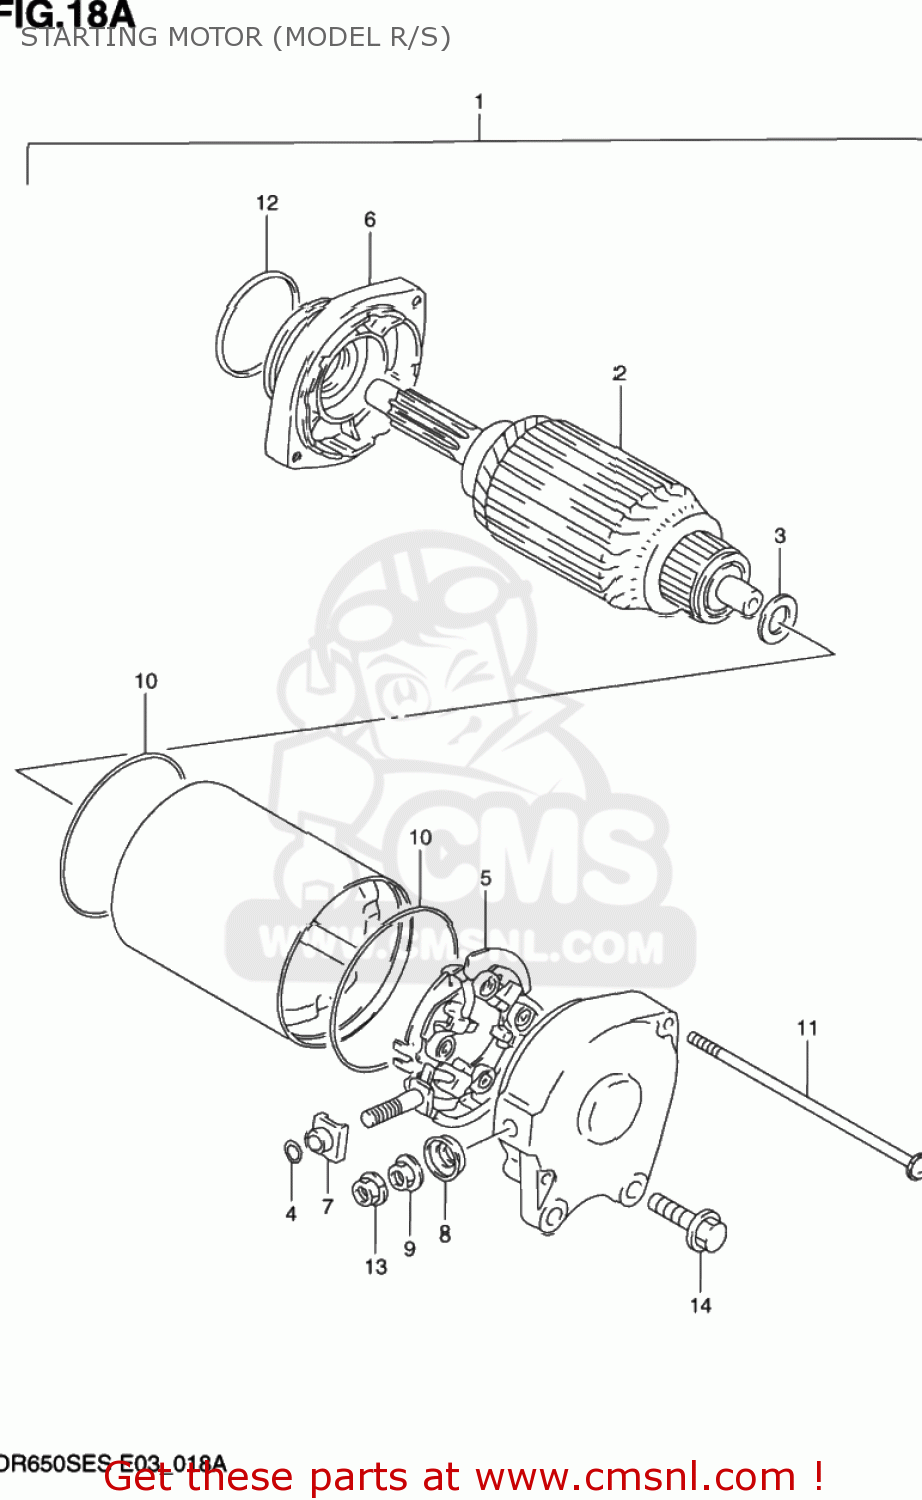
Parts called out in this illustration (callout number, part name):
1	MOTOR ASSEMBLY,STARTING
2	ARMATURE
3	SHIM,ARMATURE
4	O RING
5	HOLDER SET,BRUSH
6	BRACKET SET
7	BUSHING
8	BUSHING
9	NUT
10	O RING
11	BOLT
12	O-RING (D:2.0)
13	NUT
14	SCREW
